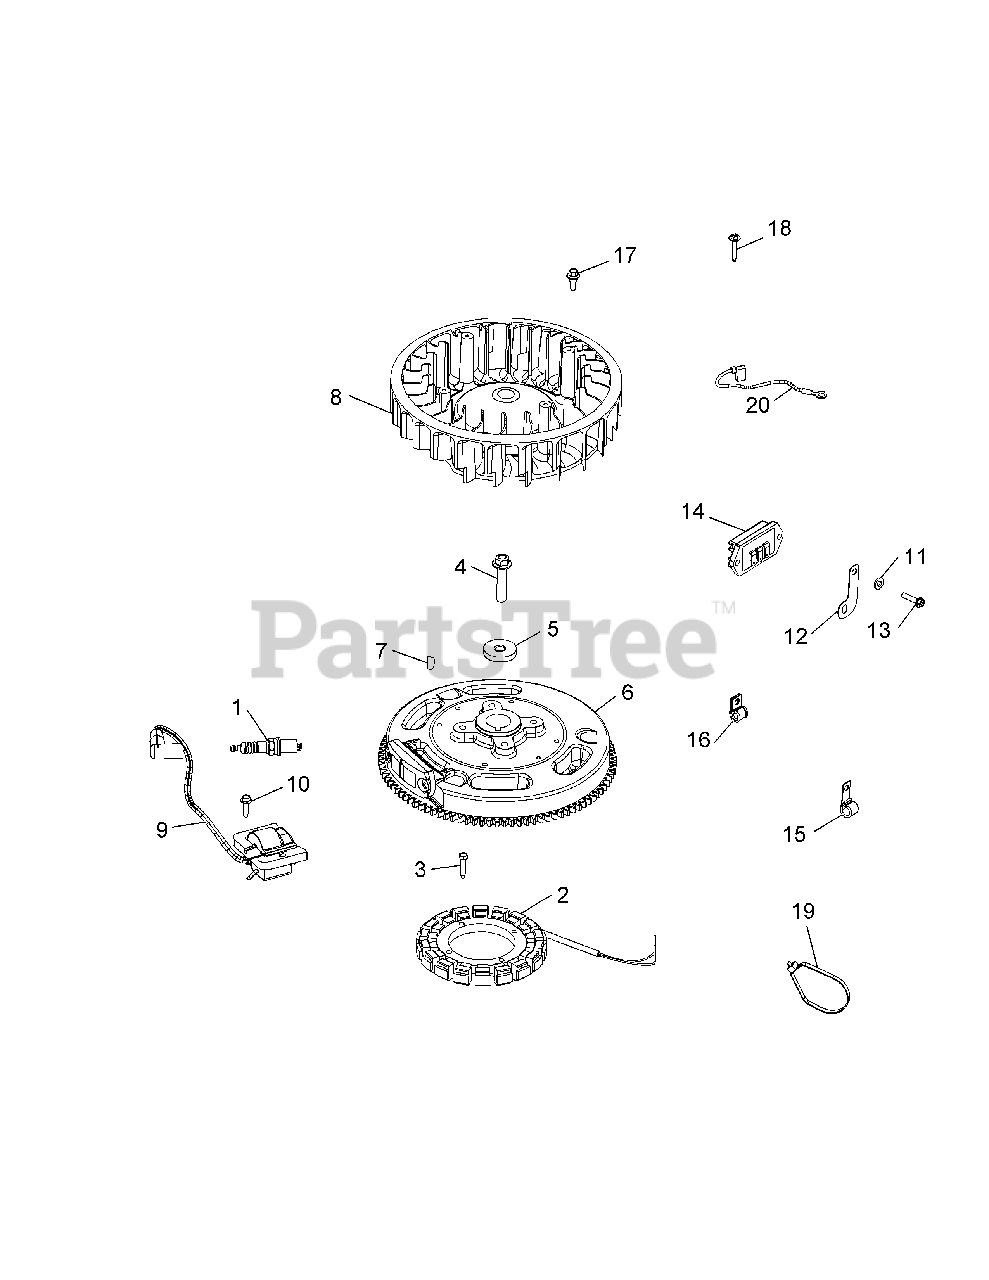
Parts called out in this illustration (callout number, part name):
2	15 Amp Stator Kit
3	Thread Forming Screw
4	Flange Screw, M10 x 1.5 x 45
5	Flat Washer, 13/32"
7	Key, 3/16 x 5/8
9	Ignition Module Kit
10	Thread Forming Screw
11	Flat Washer, 1/4
12	Ground Strap Bracket
13	Hi-Lo Hex Flange Screw
14	Rectifier Regulator
15	Cable Clip
17	Shoulder Bolt
18	Flange Screw, M4 x .7 x 25
